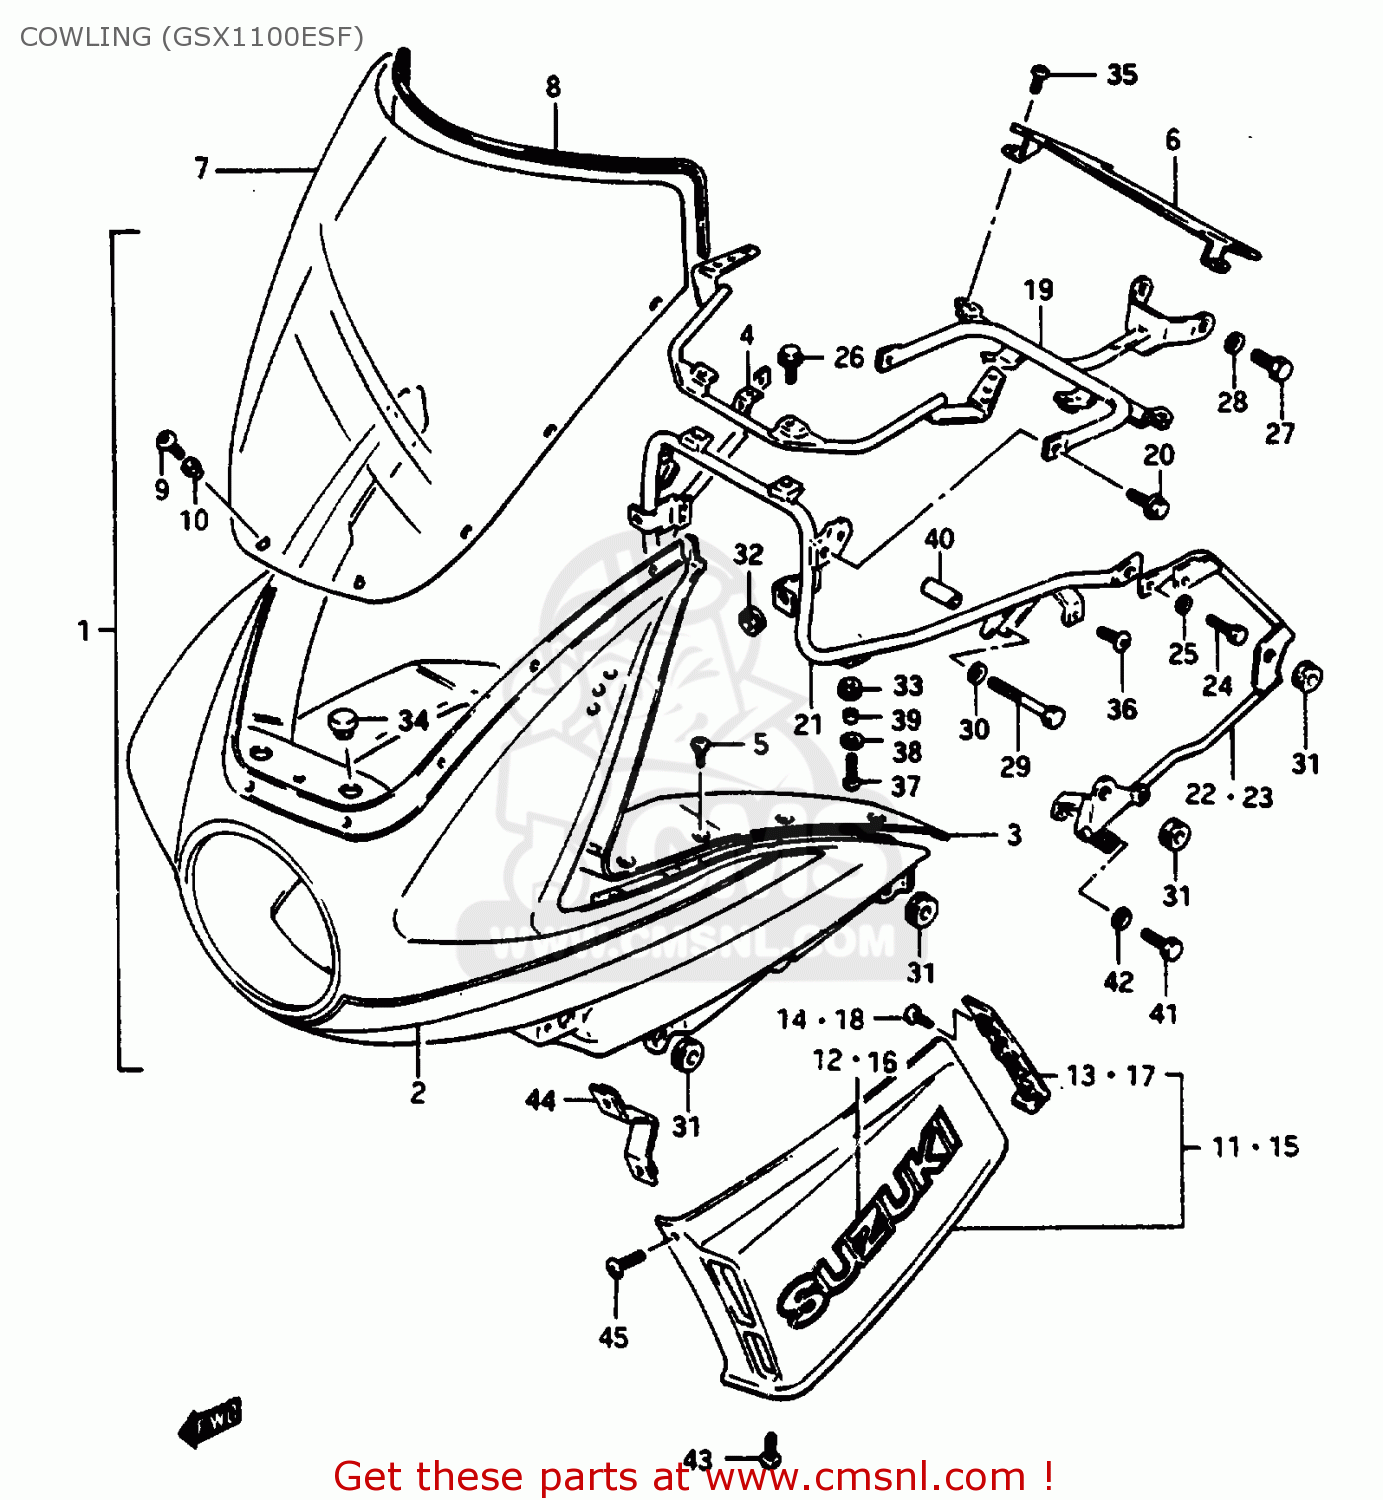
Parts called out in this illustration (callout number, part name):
1	COWLING ASSY (WHITE/RED)
2	TAPE SET
3	PANEL,COWLING
4	BRACE,COWLING BODY
5	SCREW, PANEL
6	COVER,METER,REAR
7	SCREEN
8	MOLDING
9	SCREW(5X20)
10	CUSHION
11	COVER,RH
12	EMBLEM
13	PANEL,COWL SIDE COVER RR RH
14	SCREW
15	COVER,LH
16	EMBLEM
17	PANEL,COWLING SIDE COVER
18	SCREW
19	BRACE,COWLING,FRONT
20	BOLT
21	BRACE,COWL RR
22	BRACE,COWLING SIDE,RIGHT
23	BRACE,COWLING SIDE,LEFT
24	BOLT 6X16
25	WASHER,LOCK
26	BOLT
27	BOLT
28	WASHER,LOCK,8.
29	BOLT
30	WASHER,LOCK,8.
31	CUSHION
32	CUSHION
33	CUSHION
34	PLUG(OD:22)
35	SCREW
36	SCREW 6X12
37	SCREW, CENTER
38	WASHER(6.5X18X1)
39	SPACER (6.1X9X9)
40	SPACER (8.6X13.8X35)
41	BOLT
42	WASHER,LOCK,8.
43	SCREW
44	BRACE,SIDE,FRONT
45	SCREW
